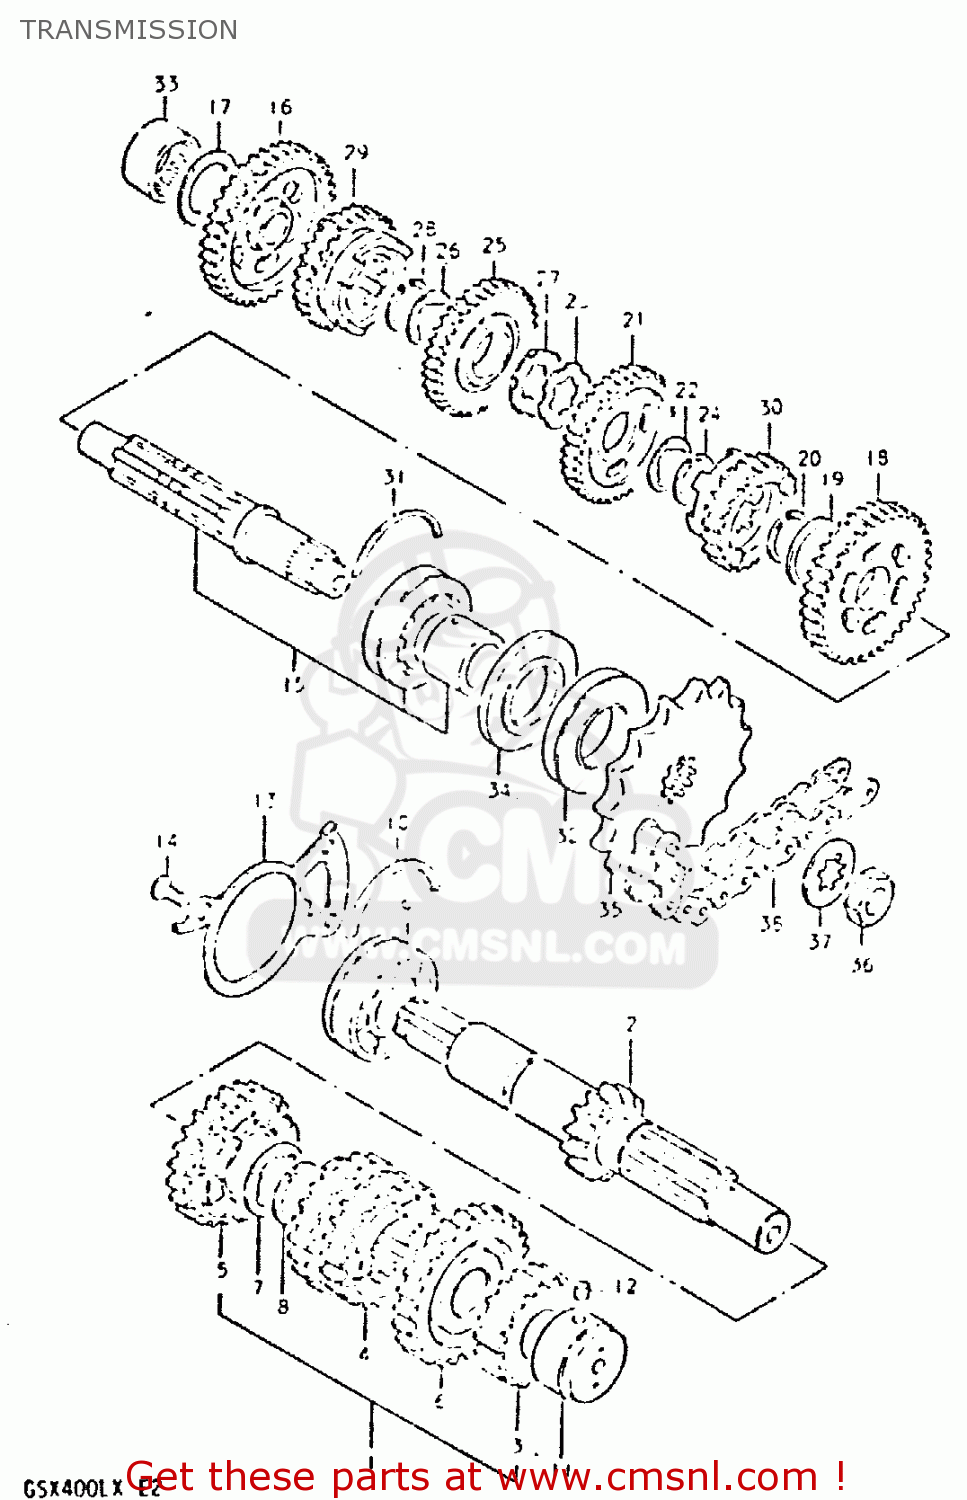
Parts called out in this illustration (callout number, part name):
1	SHAFT,COUNTER
2	SHAFT,COUNTER
3	GEAR,2ND DRIVE(NT:18)
4	GEAR,THIRD DRIVE
5	GEAR,FIFTH DRIVE
6	GEAR,SIXTH DRIVE
7	WASHER
8	CIRCLIP
9	BEARING(25X62X17)
10	C-RING
11	ROLLER BEARING (20X34X2
12	PIN
13	PLATE,COUNTERSHAFT BEARING
14	SCREW
15	SHAFT,DRIVE
16	GEAR,FIRST DRIVEN
17	WASHER
18	GEAR,SECOND DRIVEN
19	WASHER
20	CIRCLIP
21	GEAR,THIRD DRIVEN
22	WASHER,LOCK
23	WASHER,LOCK
24	CIRCLIP
25	GEAR,FOURTH DRIVEN
26	WASHER,LOCK
27	WASHER
28	CIRCLIP
29	GEAR,5TH DRIVEN(NT:25)
30	GEAR,SIXTH DRIVEN
31	C-RING
32	SEAL,OIL(32X64X8)
33	ROLLER BEARING (20X34X2
34	SEAL,OIL(32X62X5.5)
35	SPROCKET,ENGINE(NT:16)
36	NUT
37	WASHER
38	CHAIN ASSEMBLY,DRIVE
